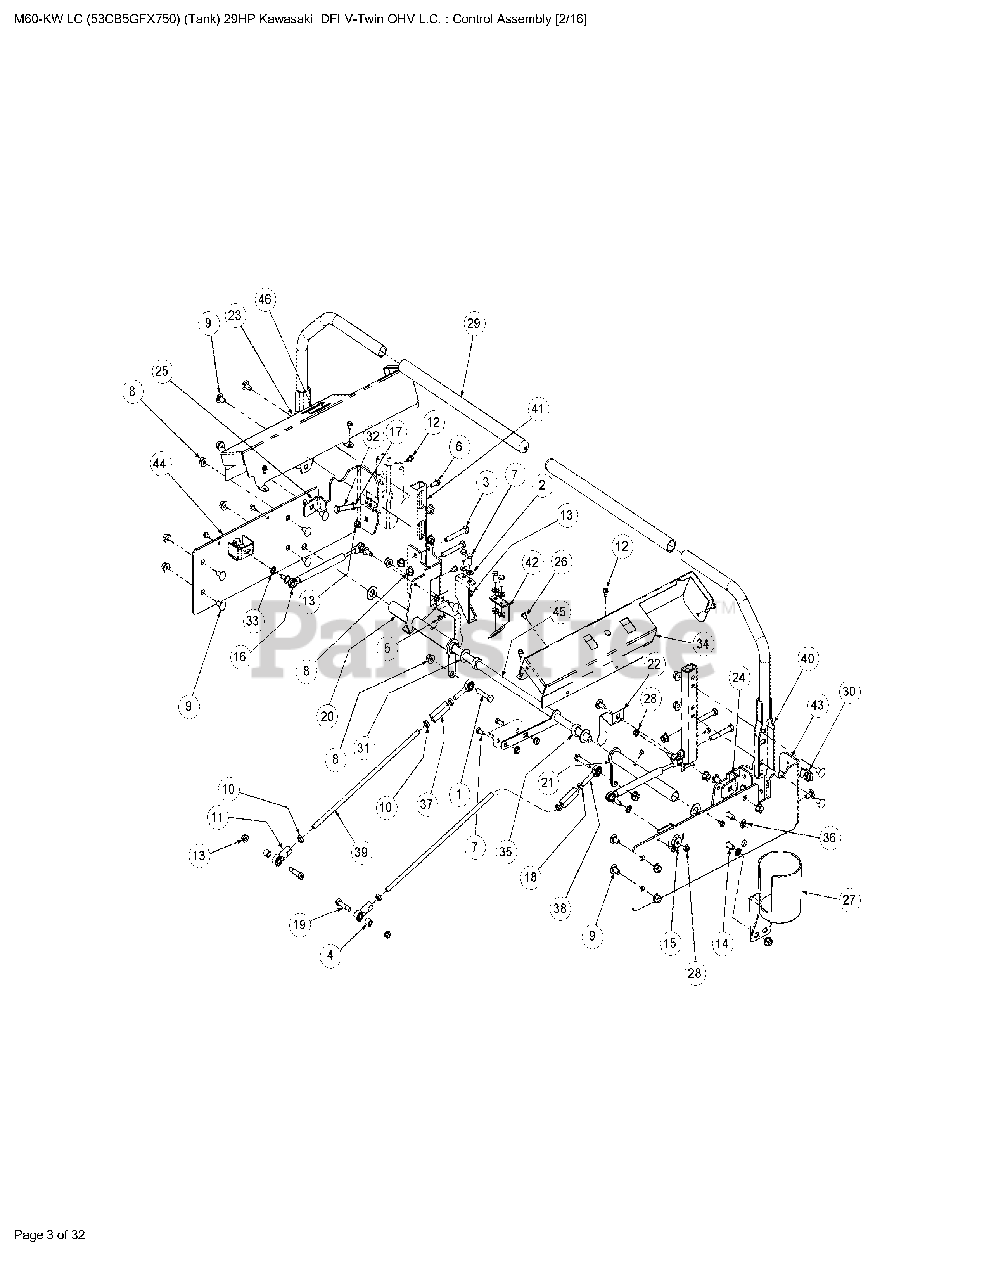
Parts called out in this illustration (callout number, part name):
1	Capscrew, 3/8-16 x 1-1/4
2	Flat Washer, 5/16
3	HHCS, 3/8-16, 2.25
4	Spacer, .625 OD x .385 ID x 1/2
5	Grease Fitting, 90 degree
6	HHCS, 5/16-18 x 1.0
7	Hex, Cap Screw, 5/16-18 x 3/4
8	Hex Nut, 3/8-16, Lock Flange
9	Carriage Bolt, 3/8-16 x .75
10	Hex Jam Nut, 3/8-24
11	B/Joint, 3/8-24, Right Hand Female
12	Screw, TT, 1/4-20, 0.5, Hex Index Washer
13	Nut, Lock, HexFlange, 5/16-18
14	Carriage Bolt, 3/8-16 x 1
15	Belle Washer, .325 x .930 x .045
16	Cylinder Return to Neutral
17	Nut, 3/8-16, Jam
18	Nut, 3/8-24, Jam, LH Third
19	Screw, Shoulder Control Rod
20	Hub Assy, Control LH Bearing
21	Hub Assy, Control RH Bearing
22	Lever, Safety Switch
23	Control Panel, LH
26	Screw Button Head, 1/4-20 x .5
27	Cup Holder Assembly
28	Nut, Hex, Center Lock, M8
29	Grip, 1.0
30	U-Nut, 3/8-16, .75
31	Flat Washer, 5/8 Nylon
32	HHCS, 3/8-16, 3.00
33	External Washer, 3/8
34	Control Panel, RH
35	Shaft Collar
36	Push Retainer
37	Turnbuckle
38	B/Joint, 3/8-24, Left Hand Female
39	Control Rod
40	Lapbar, Handle Assembly
41	Mounting Handle
42	Switch Mounting Bracket, Lapbar
43	Side Panel, Control, Right
44	Side Panel, Control, Left
45	Shaft Collar Brake Steering
46	Plate, Light Indicator
